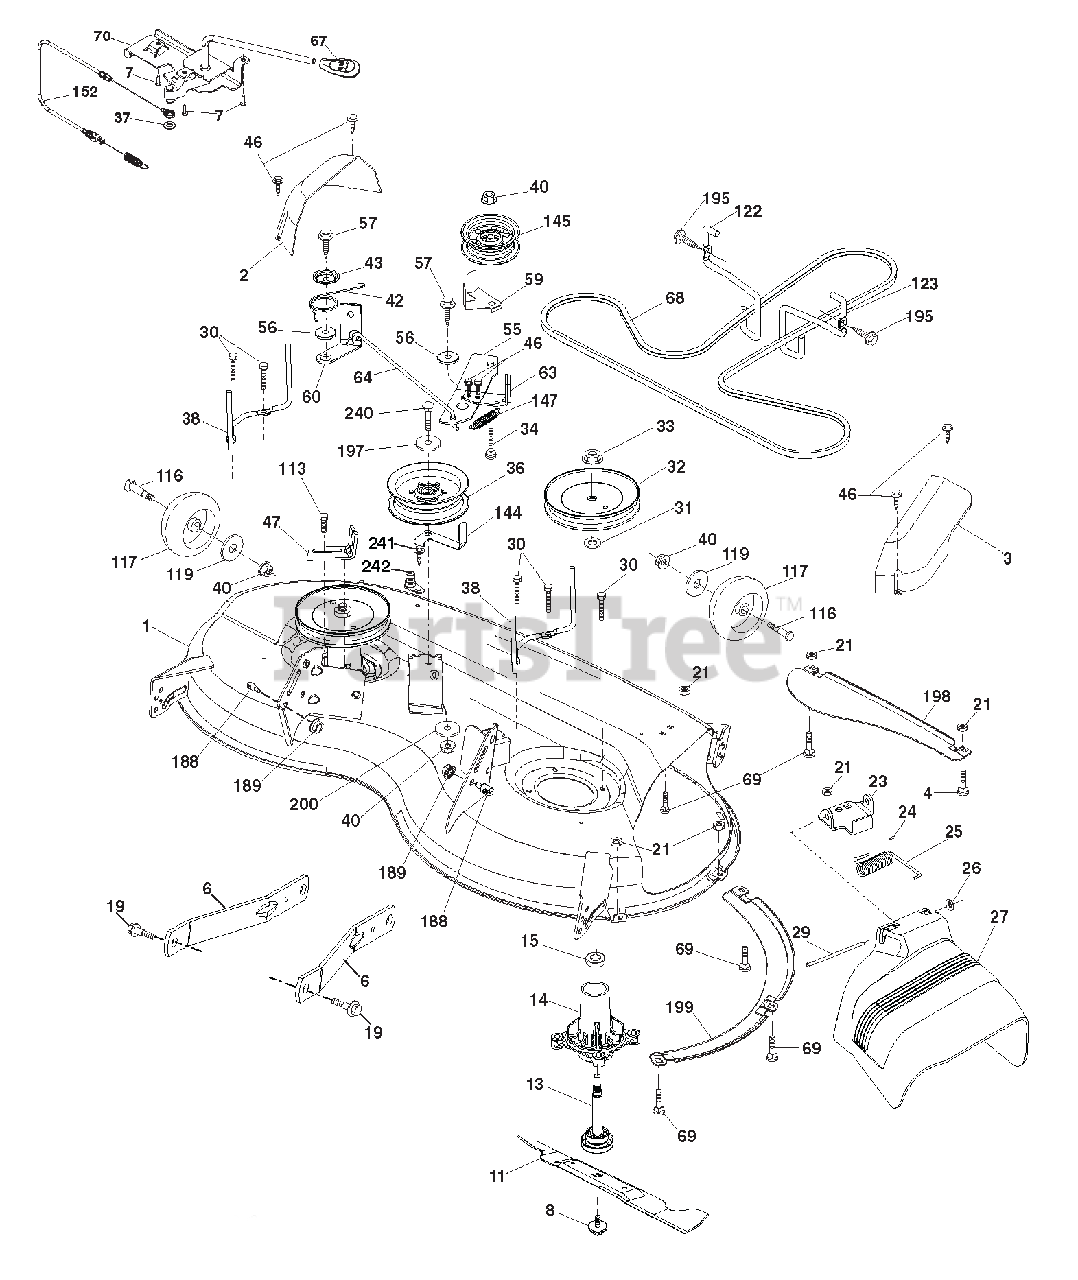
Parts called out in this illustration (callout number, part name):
1	MOWER HOUSING
2	COVER.MANDREL.LH.46"
3	COVER.MANDREL.RH.46"
4	BOLT.HEX.HD.1/4-20UNC X 3/4
6	ARM.SUSPENSION.MOWER.REAR.LD
8	BOLT/WASHER ASM.7/16-20.UNF
11	BLADE.MOWER.46"HI LIFT BAGGER
13	SHAFT ASM.MNDRL.N/GREASEABLE38
14	HOUSING.MANDREL.4PT.SERVICE
15	BEARING.BALL.MANDREL
19	BOLT.SHOULDER
21	Nut, Hex, Crownlock 5/16-18
23	BRACKET.DEFLECTOR.38/42"2005
24	CAP.SLEEVE..80X.112.BLK.MOWER
25	SPRING.TORSION.DFL.38/42/46.GR
26	NUT.PUSH.PHOS.& OIL
27	SHIELD.DEFLECTOR.MOWER 46"BLK
29	ROD.HINGE.42/46"
30	SCREW.THD ROLL.DOD PT.HEX
31	WASHER.SPACER.MANDREL
32	PULLEY.MANDREL.5.438 PD.42"
33	NUT.FLANGE.LOCK.TOP
34	BOLT.CARR.SH.3/8-16X1-1/2.GR5
36	PULLEY.IDLER 48"PRIMARY
37	WASHER.13/32 X 13/16 X 16 GA.
38	KEEPER.BELT.MANDREL.PULLEY
40	Nut, Hex, Flangelock 3/8-16
42	SPRING.TORSION.BRAKE
43	SPRING.TORSION.RETAINER
46	SCREW.THD.ROLL.1/4-20 X 5/8
47	BRACKET.CLUTCH.CABLE
55	IDLER.ARM
56	SPACER.RETAINER
57	SCREW.3/8-16X1.SMGML.TAP/R.BLK
59	GUARD.TUV.IDLER
60	ARM.BRAKE.MOWER.38/46"LH.TEX
63	ARM.BRAKE.MOWER
64	LINAGE.ASM.BRAKE
67	HANDLE.CLUTCH.CABLE.LT TEX.428
68	V-BELT.DRIVE.MWR.MECHANICL.46"
69	BOLT.RDHD.SQNK.5/16-18 X 5/8
70	CLUTCH.ASM.MANUAL
113	BOLT.5/16-18HEX.WHS.HD.LCKSERR
116	BOLD SHLD "A" 2.41 "B" 1.66
117	WHEEL.GAGE.HALF.SPOKED
119	Washer 3/8 x 7/8 x 14 Ga.
122	KEEPER.BELT.ENGINE.LH.LT.TEX
123	KEEPER.BELT.ENGINE.RH.LT.TEX
144	KEEPER.BELT.MOWER
145	PULLEY.IDLER.4.50.RAW
147	SPRING.RETURN.DECK.38/46"
152	CABLE.CLUTCH.MANUAL
188	STUD.FASTNER.W/'D'ANTI-ROTATIO
189	Nut, Lock Hex Flange 5/16-18 u
195	SCREW.HEXWSH THDR3/8-16X3/4.BL
197	Washer 13/32 x 13/16 x 12 Ga.
198	BAFFLE.CENTER.FRONT
199	BAFFLE.FRONT.RH
200	WASHER.13/32 X 1 X 1/2.11GAHRD
240	BOLT.FIN.HEX.3/8-16X 2-1/4 GR5
242	PORT WASHOUT
